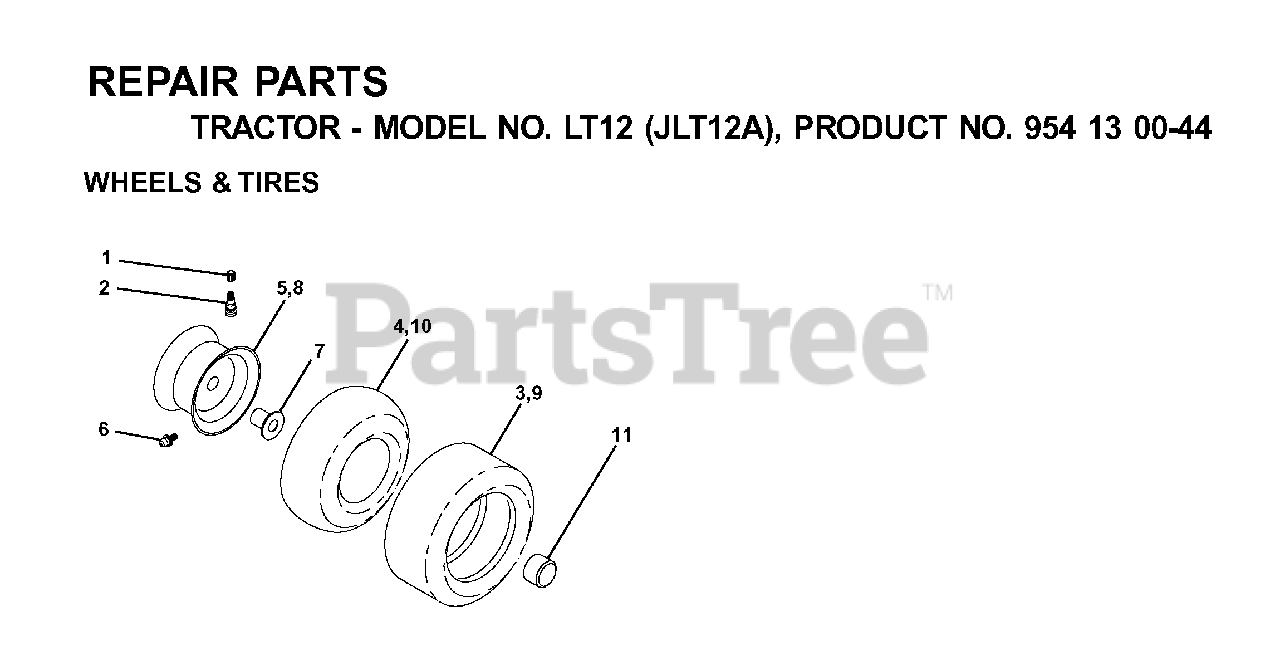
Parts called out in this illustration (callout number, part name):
1	VALVE CAP
2	VALVE STEM LT
3	TIRE HEAVY DUTY
4	TUBE.5.3/4.5/6
5	RIM ASM 6" FRONT SILVER
6	FITTING LT
7	BEARING T
8	RIM ASM 8" REAR SILVER
9	TIRE
10	TUBE
11	CAP, AXLE BLK
